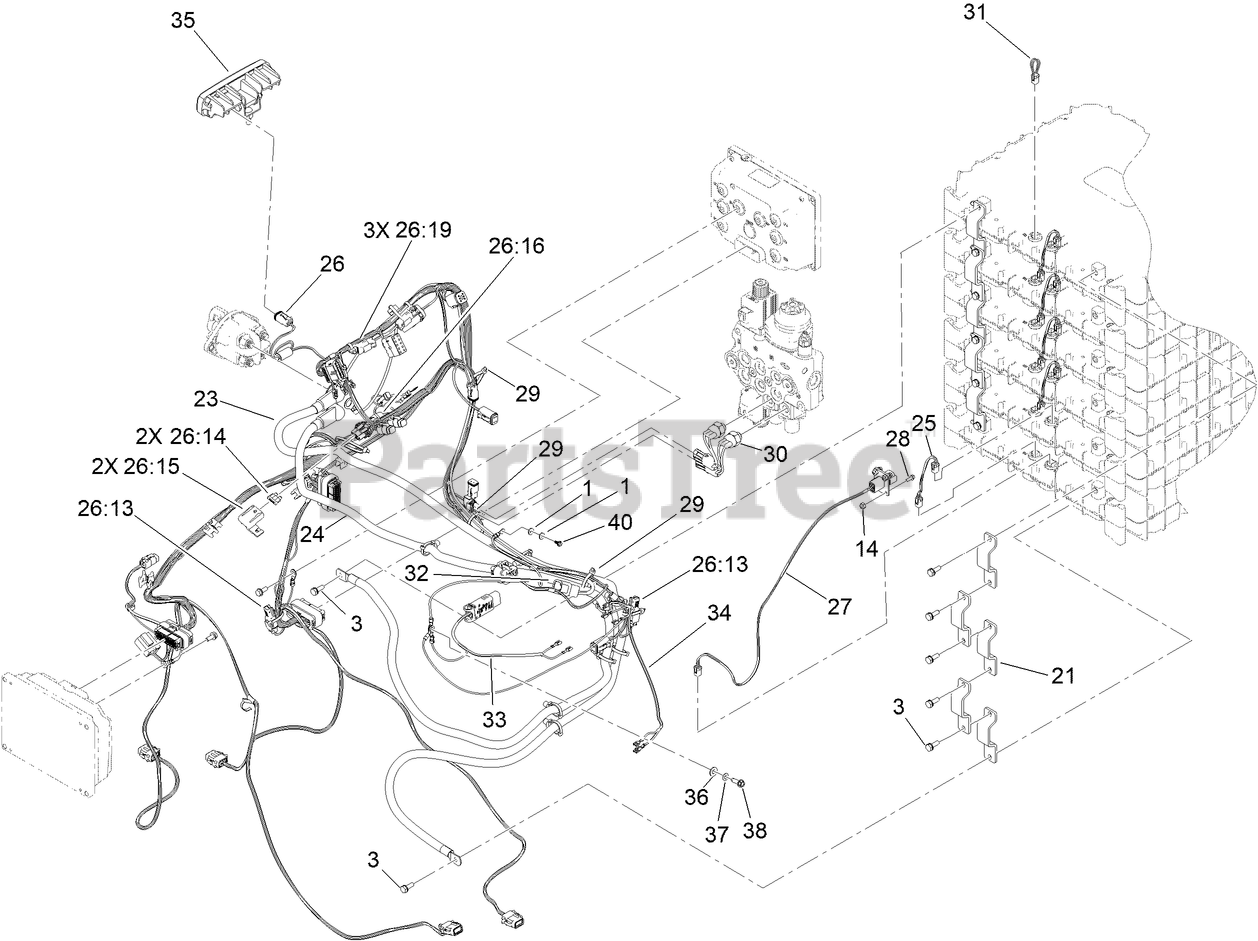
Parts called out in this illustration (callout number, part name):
1	WASHER-FLAT
3	SCREW-SEMS
14	NUT-LOCK
21	BAR-BUS, 400A
23	CABLE-BATTERY, RD ASM
24	CABLE-BATTERY, BK ASM
25	HARNESS-WIRE, DATA INTERFACE
26	HARNESS-WIRE, MAIN
26:13	RESISTOR-120 OHM
26:14	FUSE-BLADE, 10A
26:15	COVER-APTIV, MODIFIED
26:16	CAP-PLUG, 3 WAY
26:19	CAP-DUST, 2 WAY
27	HARNESS-WIRE, PACK COMM
28	SCREW-HHF, SERRATED
29	TIE-CABLE
30	SWITCH-BALL
31	HARNESS-WIRE, CAN TERMINATOR
32	HARNESS-WIRE, JUMPER
33	HARNESS-WIRE, AC CHARGER
34	HARNESS-WIRE, AC CHARGER
35	LIGHT-WORK, LED BAR
36	WASHER-FLAT
37	WASHER-SPRING
38	SCREW-HWHTF
40	SCREW-GROUND
